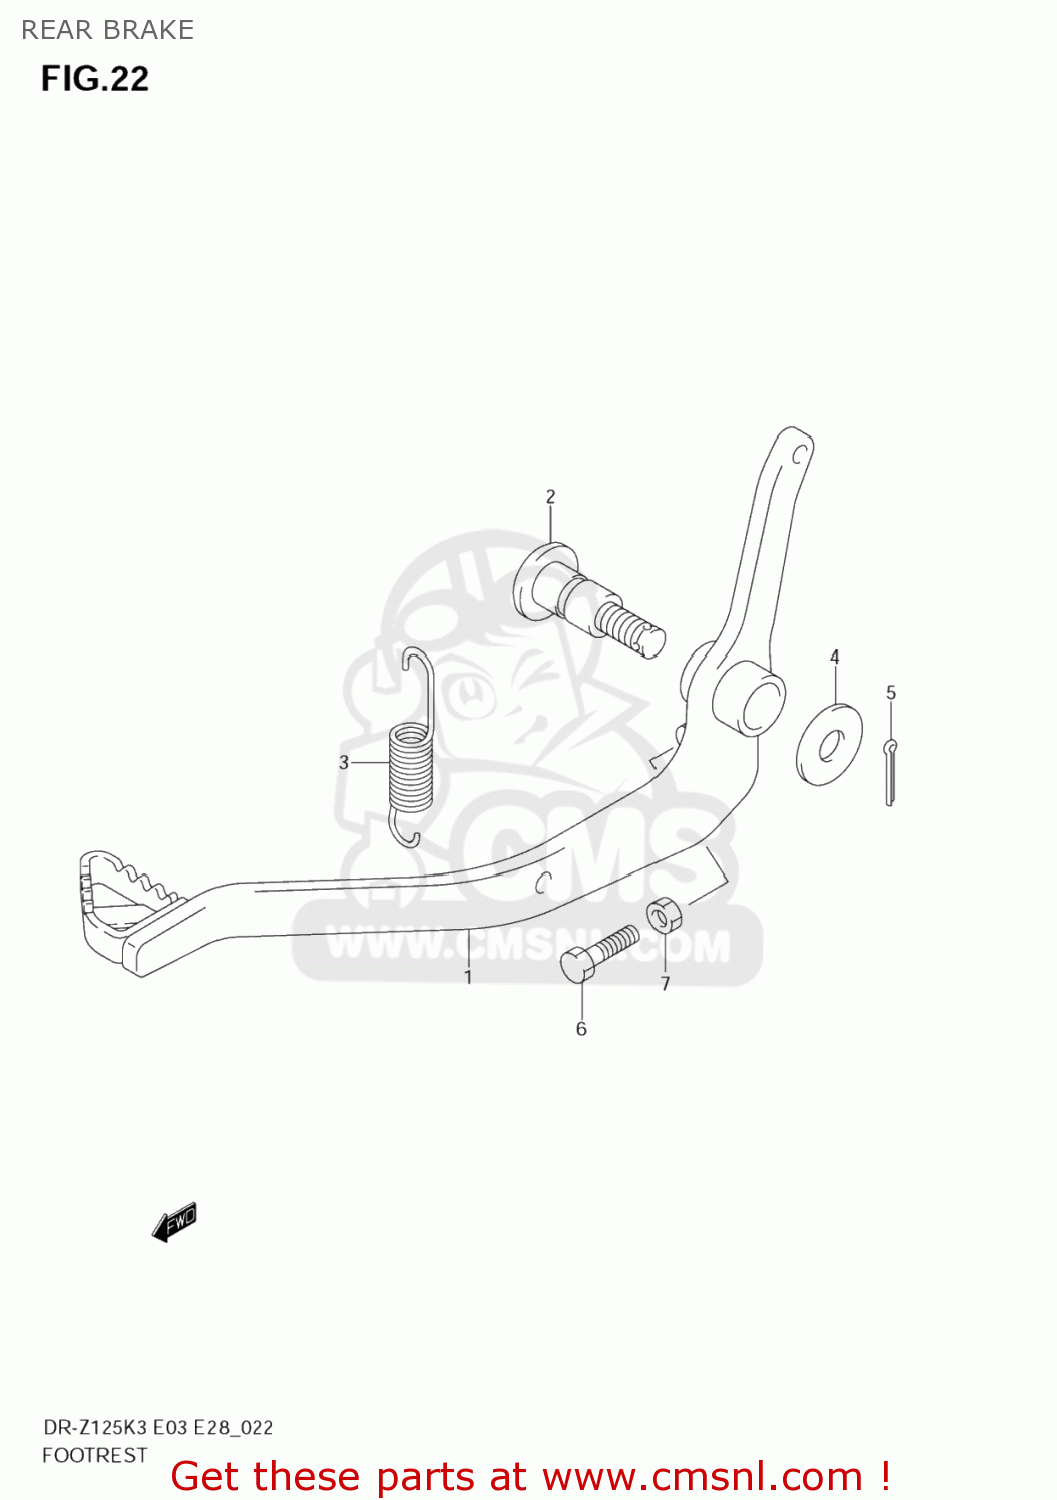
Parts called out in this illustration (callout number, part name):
1	PEDAL,BRAKE
2	SHAFT,BRAKE PEDAL
3	SPRING
4	WASHER
5	PIN 20X20
6	BOLT(6X18)
7	NUT 6MM
